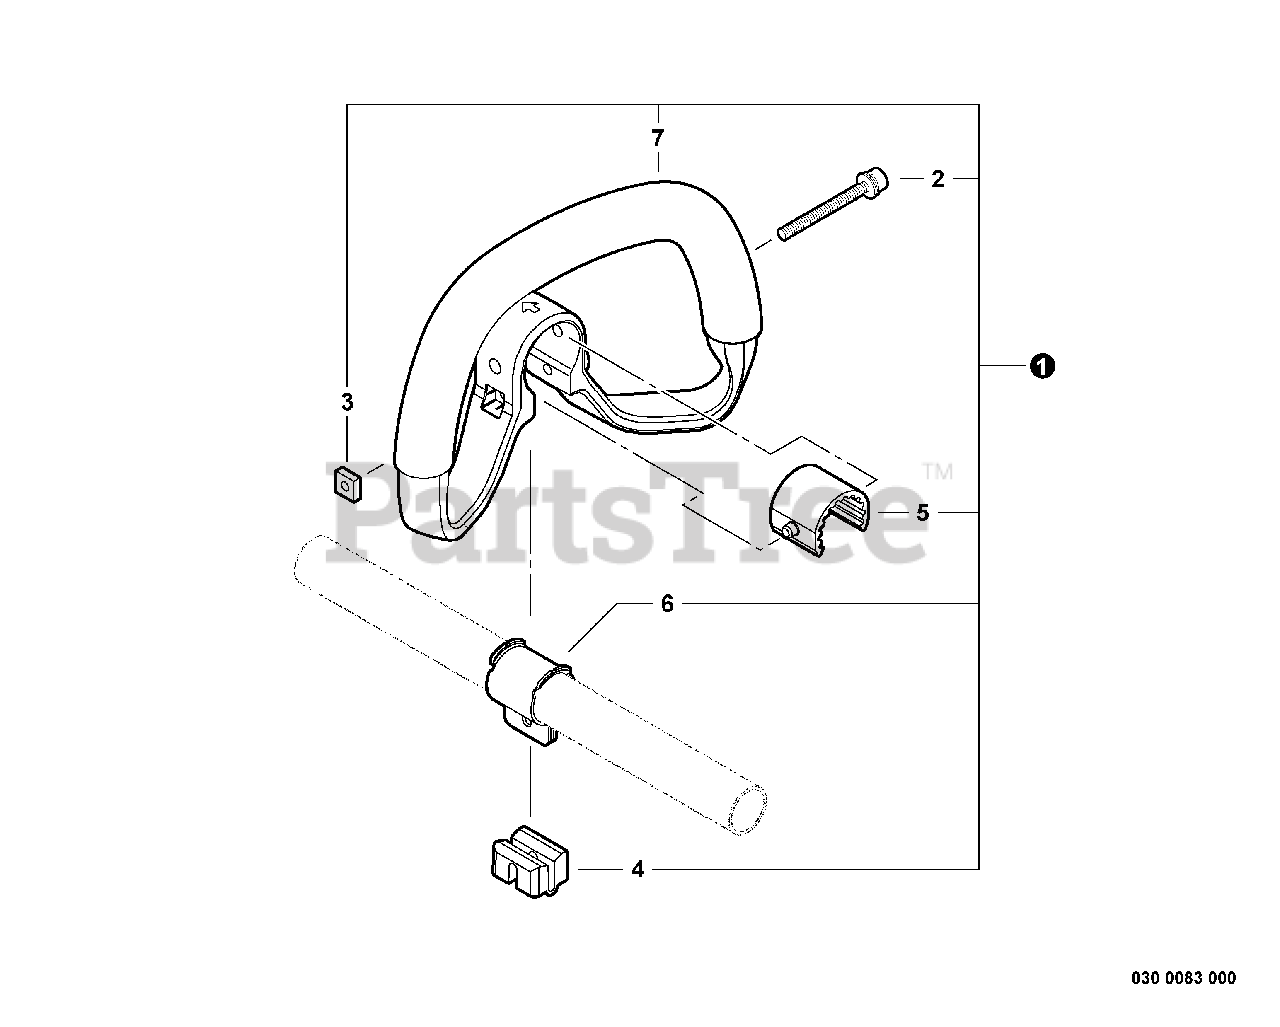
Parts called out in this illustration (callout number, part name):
1	HANDLE KIT - FRONT
2	SCREW - 5X40
3	NUT - 5
5	CUSHION
6	BRACKET, HANDLE
7	HANDLE - FRONT
